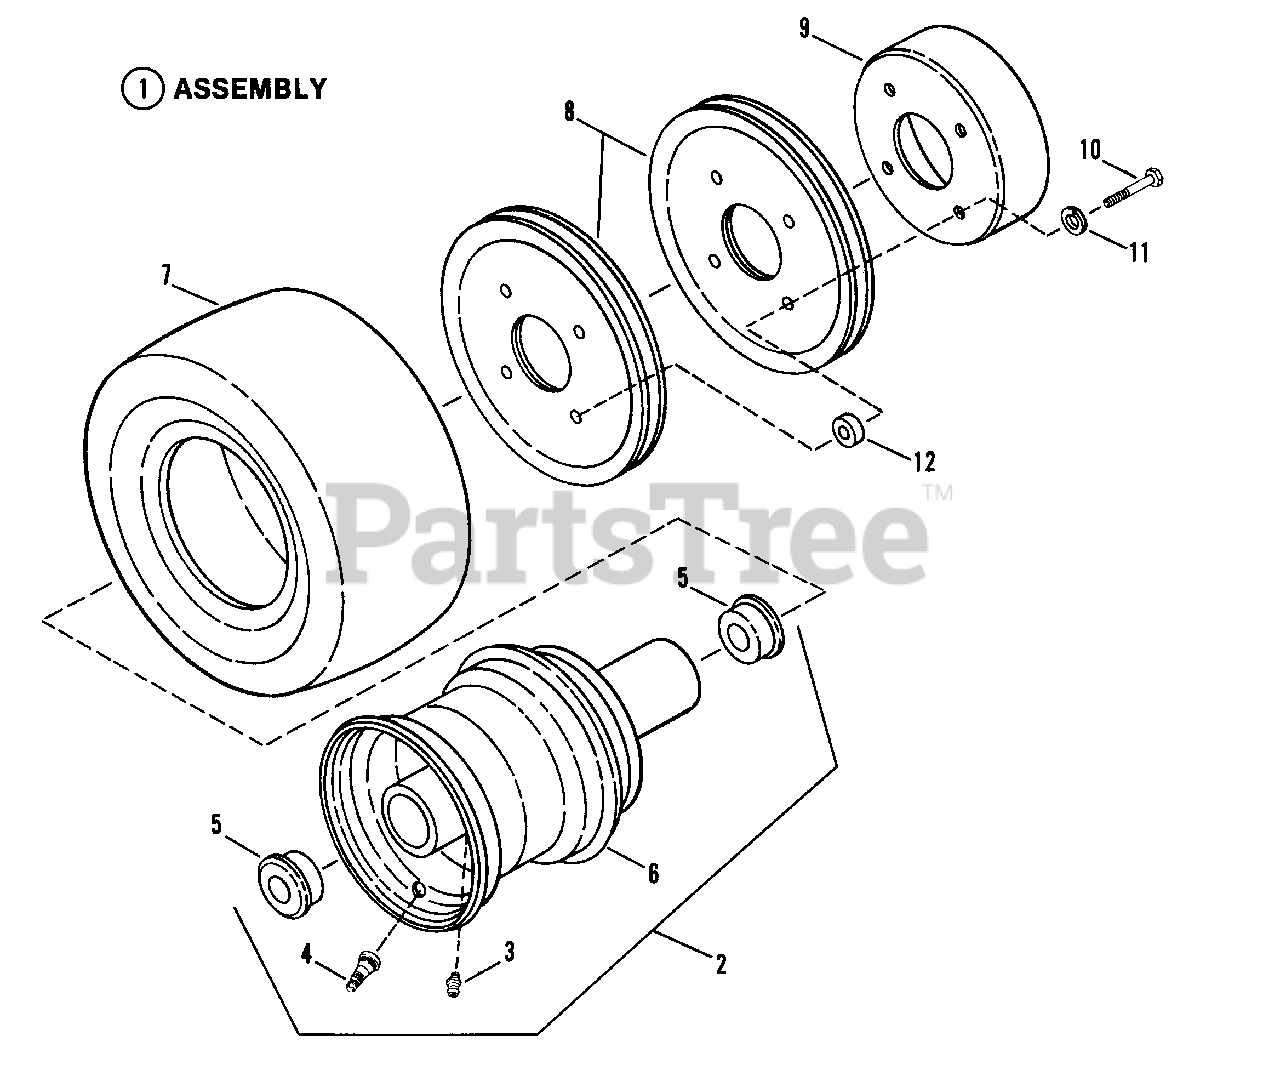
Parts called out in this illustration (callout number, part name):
1	ASSEMBLY, Rear Tire & Rim
2	ASSEMBLY, Rim
3	FITTING, Lube
4	VALVE, Air (Snap-In)
5	BEARING, Wheel
6	RIM
7	TIRE, 6.50 x 13-6, 2-Ply, Tubeless
8	PULLEY, 8"
9	DRUM, Brake
10	SCREW, 5/16-18 x 1 1/2" Hex Head Cap
11	WASHER, 5/16 Split Lock
12	SPACER
